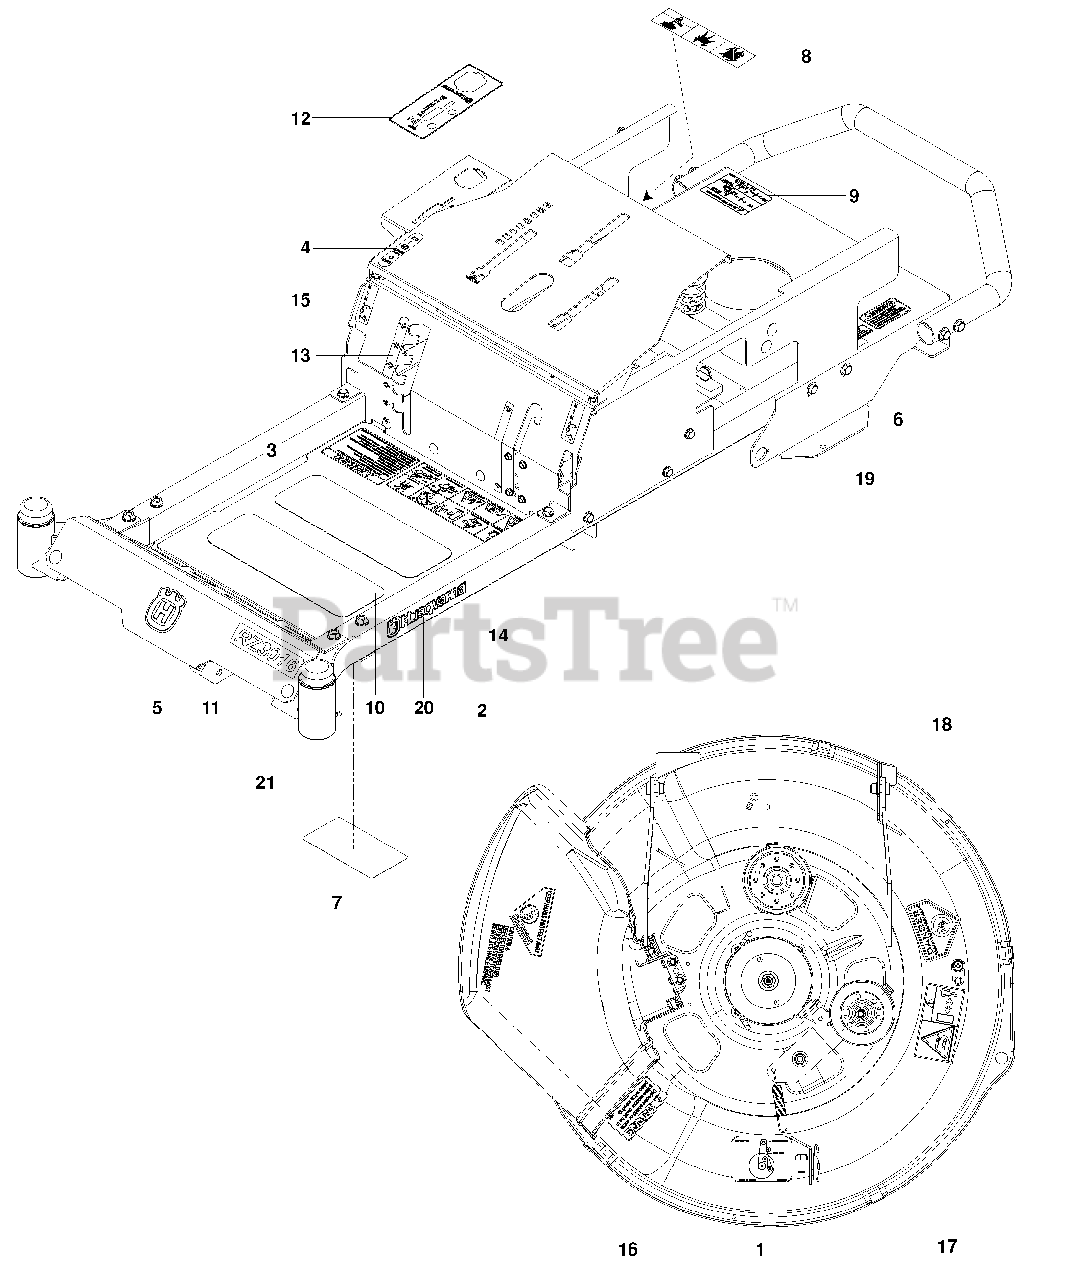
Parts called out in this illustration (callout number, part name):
1	DECAL, BELT ROUTING
2	DECAL, SAFETY WARNING
3	DECAL, WARNINGS
4	DECAL, PARK BRAKE
5	DECAL, CROWN
6	DECAL, EXHAUST WARN
7	DECAL, SERVICE
8	DECAL, BATTERY WARNING
9	DECAL, DO NOT TOW
10	PAD, ABRASIVE
12	DECAL, CONTROL PANEL
13	DECAL, DECK HEIGHT
14	DECAL, BLADE ENGAGE
15	DECAL, MOTION CONTROL
16	DECAL, DEFLECT CAUTION
17	DECAL, SEVERING
18	DECAL, BLADE WARN
19	DECAL, SPARK ARRESTOR
20	DECAL, HUSQVARNA
21	DECAL, RZ3016
